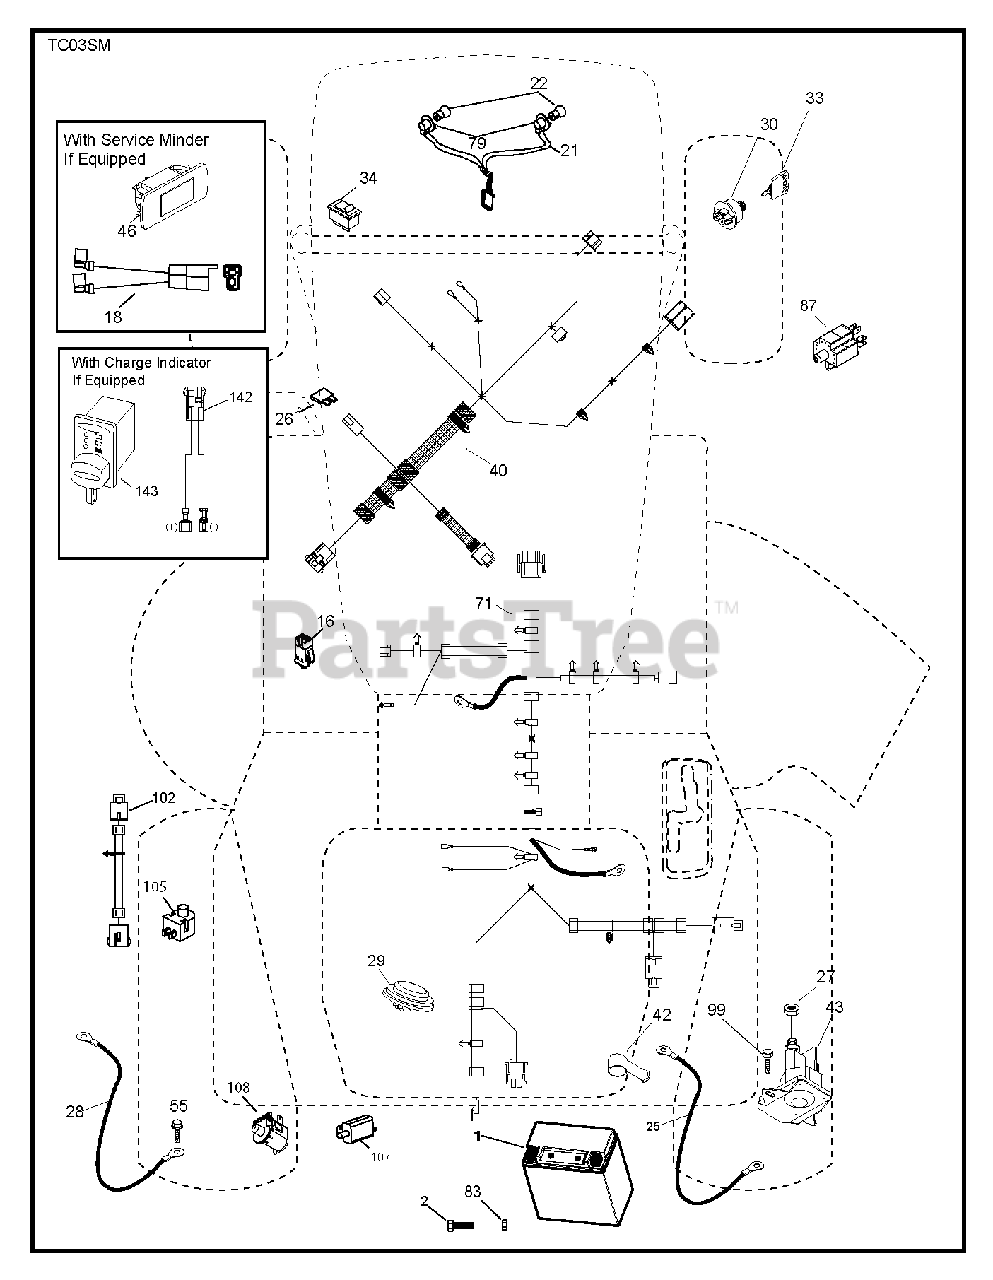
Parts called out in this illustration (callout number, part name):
1	BATTERY BATTERY 14AH 12V LEOC
2	SCREW.HEX.HEAD.CAP.M6 X1.12W
16	SWITCH INTERLOOK PUSH-IN
21	HARNESS.LIGHT W/4152J BULBS
25	CABLE.BATT.8GA.RED9.C
26	FUSE 20AMP
27	NUT
28	CABLE.BATT.BLCK10.SLV
29	SWITCH.SEAT.DELTA.OPC.
30	SWITCH.IGN.DELTA.W.LGH.ROS
33	KEY.CHAIN.BLISTER.PACK.GEN.INT
40	HARN.DASH.CRD.CC.SQ.RDSTRT
42	TERMINAL COVER
43	SOLENOID.W/BRASS.PLUNGER
55	SCREW 5/16"
71	HARNESS.CHASS.CRD.TEX.RDY.STRT
79	BULB HOLDER ASM.
83	NUT NUT SQUARE
87	RP SWITCH.RAILMOUNT.NO-NC-NC
99	SCREW HEXWSHR 1/4-20X3/4
102	HARNESS ASSY
105	REVERSE SWITCH
107	.WITCH.FULL BAGGER.INDICATOR
108	SWITCH.SNAPMOUNT.NC
142	CHARGE.PORT.PIGTAIL HARNESS
143	CHARGE.PORT
